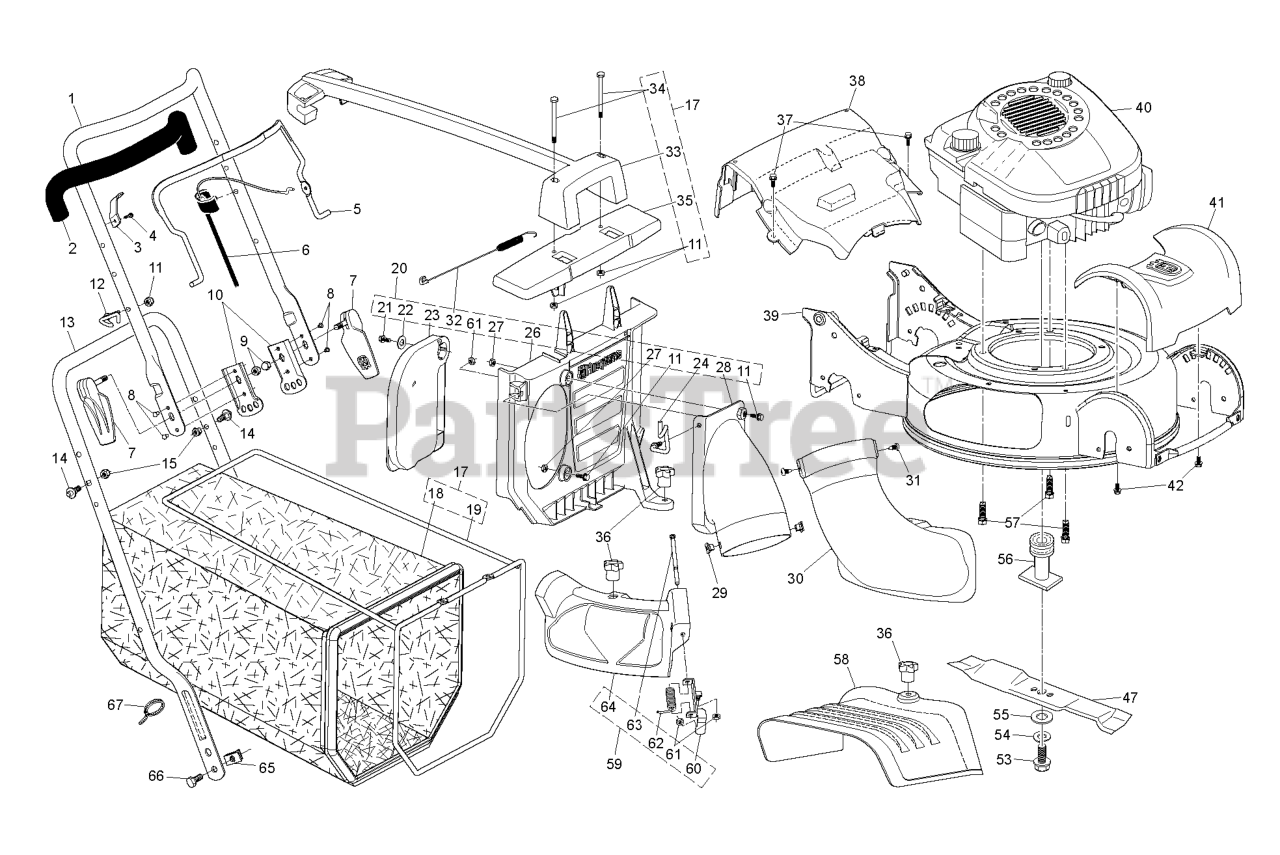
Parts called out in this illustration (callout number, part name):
2	GRIP, FOAM
3	BRACKET
5	BAIL CONTROL
6	CABLE.MZR.47.75.SNAP-IN.PU.L
7	ASM.QUICK.RELEASE
9	Locknut, Hex 1/4-20
10	BRACKET.ADJ.3POS.GREY
11	NUT
12	RB GUIDE.ROPE.STD.BLK.ZIN WSL
14	STUD.QUICK.ADJUST
15	NUT.LOCK.5/16-18
22	WASHER
27	BOLT SHOULDER
31	SCREW T-30 1/4-20 X
36	KNOB.MULCH.DOOR
37	SCREW, HEX WASHER HEAD
42	SCREW.HWH.13-16-5.8.BZP
47	BLADE.SWEPT.WING.45CM.H.TREAT
53	BOLT.HD.HEAD.3/8-24X2.50 (2 2)
54	LOCKWASHER
55	WASHER,HARDEN
56	ADAPTER.BLADE.PUSH
57	BOLT 3/8-16X1-1/8
61	NUT.HEX.FLANGE.1/4
62	SPRING.MULCH.DOOR
63	ROD.HINGE.1/4"3.82"
64	DOOR.MULCH.GREY
67	TIE GUIDE
